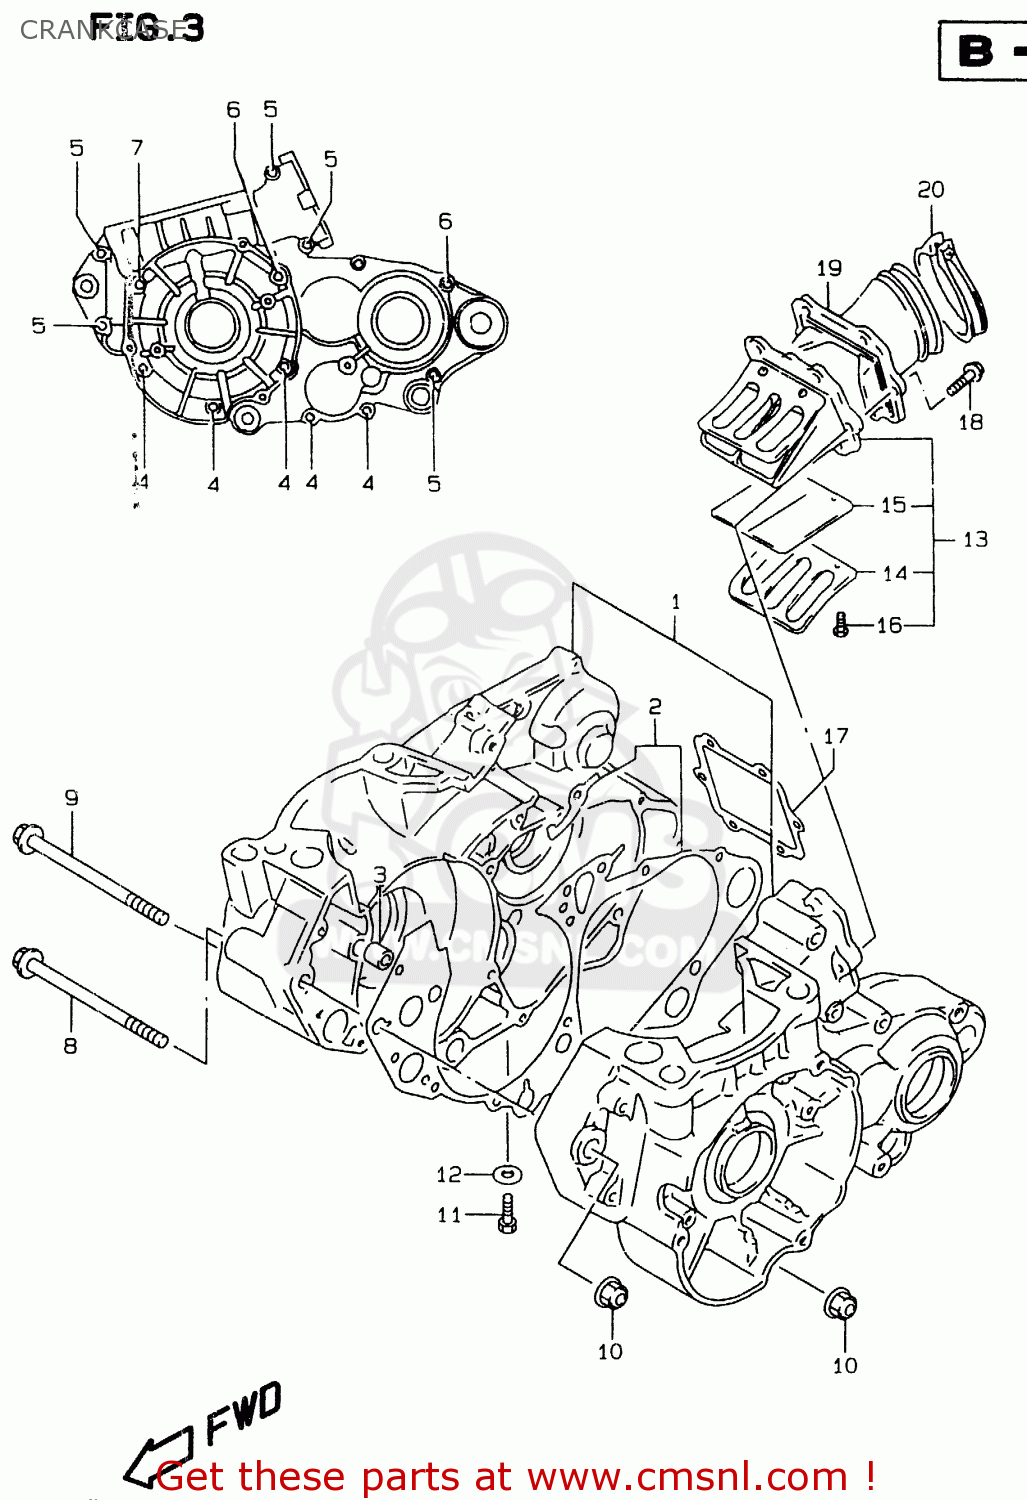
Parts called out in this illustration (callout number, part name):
1	CRANKCASE SET
2	GASKET,CRANKCASE (NAS)
3	PIN
4	BOLT
5	BOLT
6	BOLT
7	BOLT
8	BOLT(8X102)
9	BOLT(8X137)
10	NUT
11	BOLT
12	GASKET(8.2X14X1) (NAS)
13	VALVE ASSY,REED
14	STOPPER,REED VALVE
15	VALVE,REED
16	SCREW
17	GASKET,REED VALVE (NAS)
18	SCREW
19	PIPE,INTAKE
20	CLAMP
